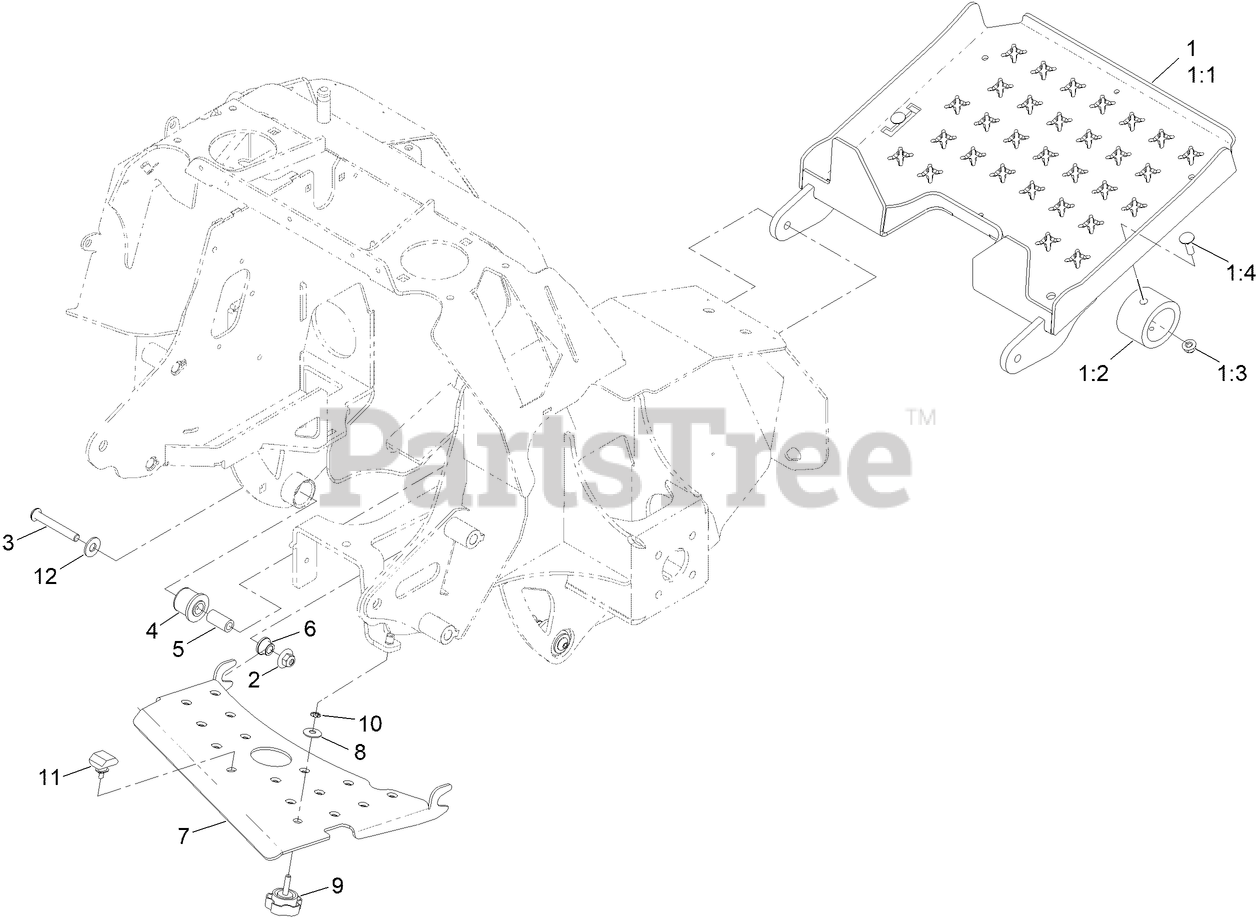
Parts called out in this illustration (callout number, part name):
1	ASM-PLATFORM
1:1	WELD-PLATFORM [BLK-TXT]
1:2	BUMPER-ISOLATOR
1:3	NUT-HF, NI
1:4	BOLT-CARR
2	NUT-FLANGE, NI
3	SCREW-HSBH
4	BUSHING-RUBBER, SUSPENSION
5	SPACER
6	BUSHING-FLANGED
7	DEFLECTOR, AIR, 36
8	WASHER-BELLEVILLE
10	NUT-RETAINING
11	BUMPER-ROPS
12	WASHER-FLAT
